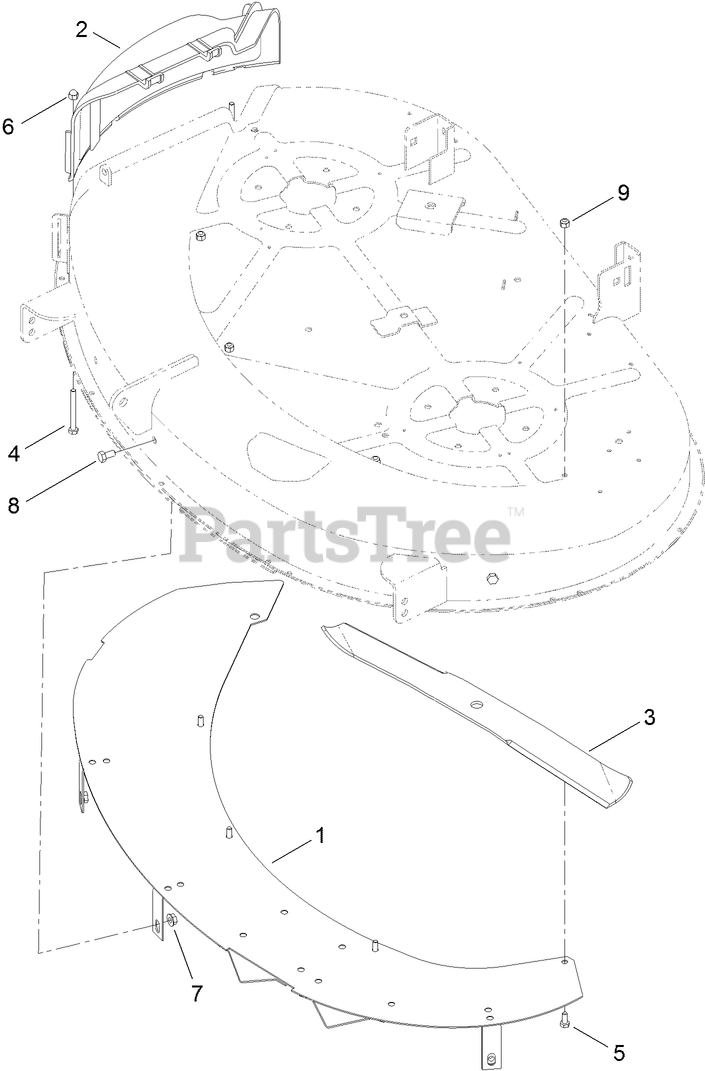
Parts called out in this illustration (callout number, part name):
1	BAFFLE UPPER ASM
2	COVER-DISCHARGE
4	SCREW-HH
5	SCREW-HH
6	NUT-CAP
7	NUT-HF
8	SCREW-HH
9	NUT-LOCK, NI
